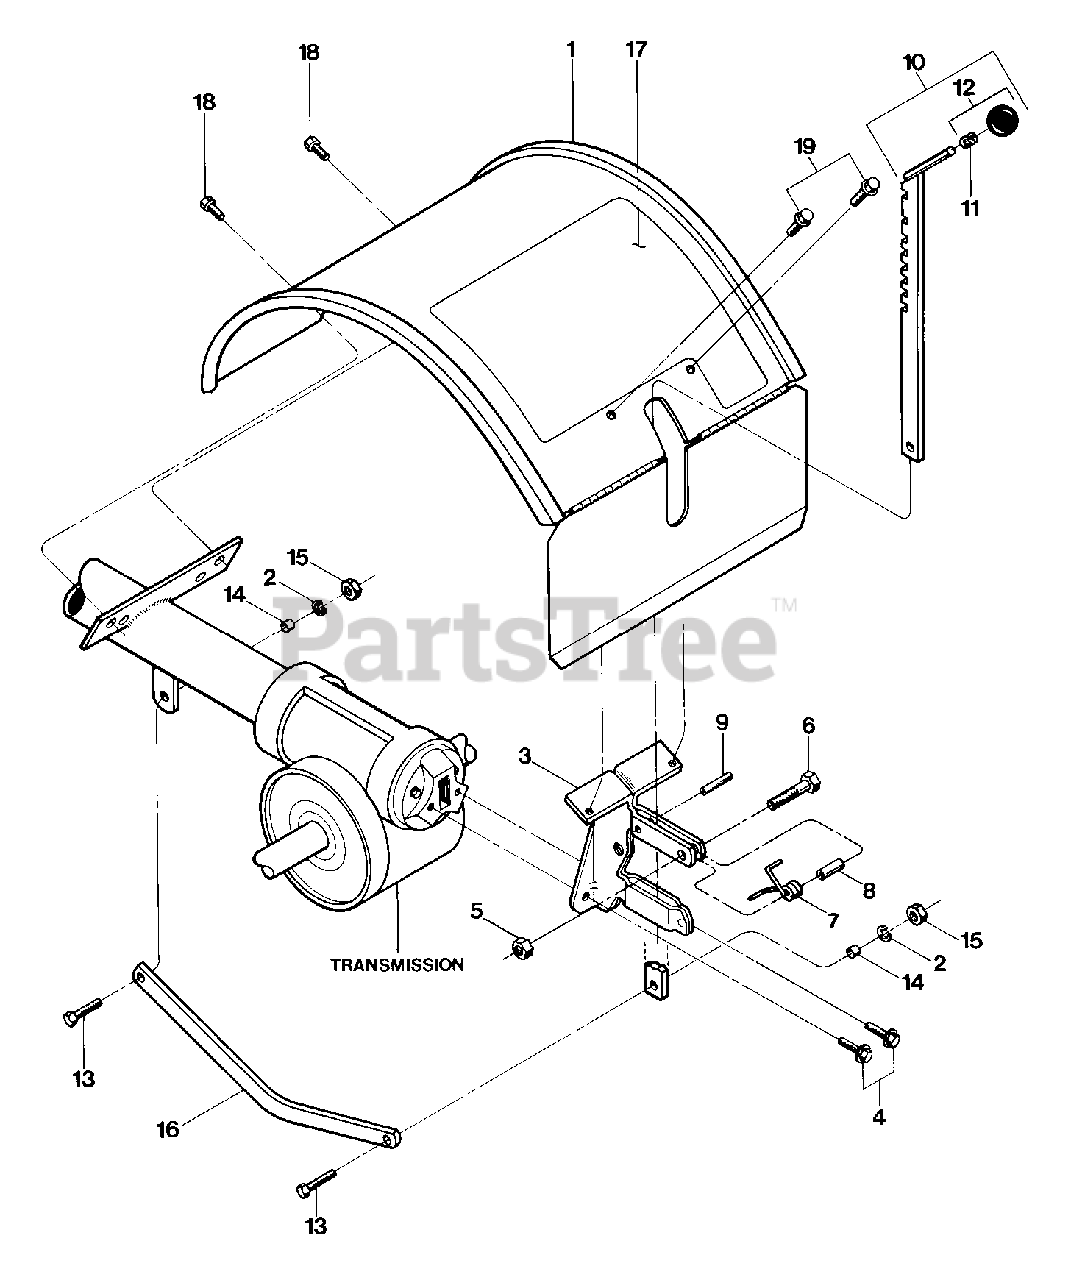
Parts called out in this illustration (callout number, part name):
1	Tine Hood
2	Lockwasher, 3/8
3	Bracket-hood & depth regulator
4	Hex Flange Screw, 5/16-18 x 5/8
5	Hex Locknut, 1/4-20
6	Hex Hd. Screw, 1/4-20 x 1
7	Spring
9	Roll Pin (spiral), 1/4 x 1
10	Depth Adjustment Bar Assembly
11	Retaining Ring (tolerance ring)
12	Knob, Depth Regulator
13	Hex Hd. Screw, 3/8-16 x 1-1/4
14	Bushing, Drag Bar
15	Hex Nut, 3/8-16
16	Drag Bar
17	Decal, operating instructions
18	Hex Hd. Screw, self-tapping, 5/16-18 x 1/2
19	Hex Flange Screw, self-tapping, 1/4-20 x 1/2
